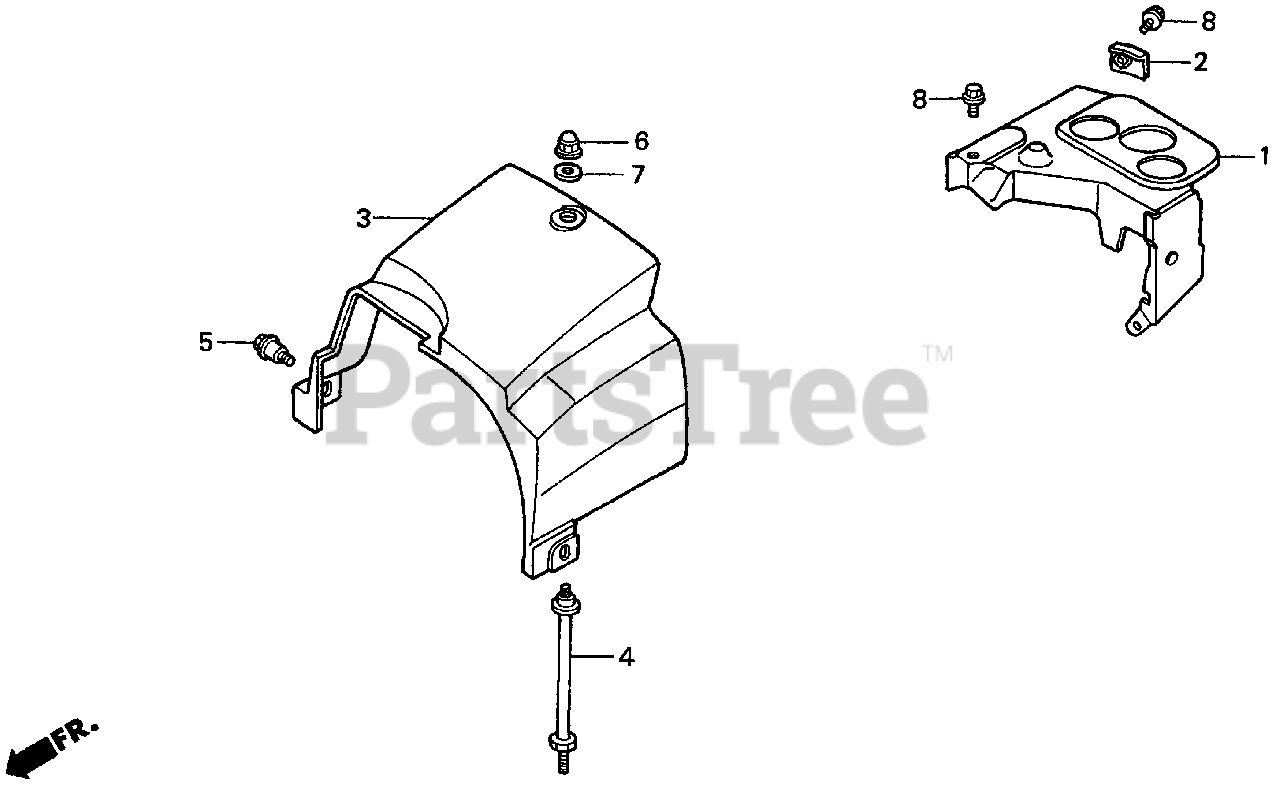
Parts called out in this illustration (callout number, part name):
1	COVER, ENGINE CONTROL
2	STOPPER, THROTTLE LEVER
3	COVER, TOP *R8* (BRIGHT RED)
4	BOLT, TOP COVER SETTING
5	BOLT, FLANGE (6MM)
6	NUT, CAP (6MM)
7	WASHER, PLAIN (6X16)
8	BOLT, FLANGE (6X10)
